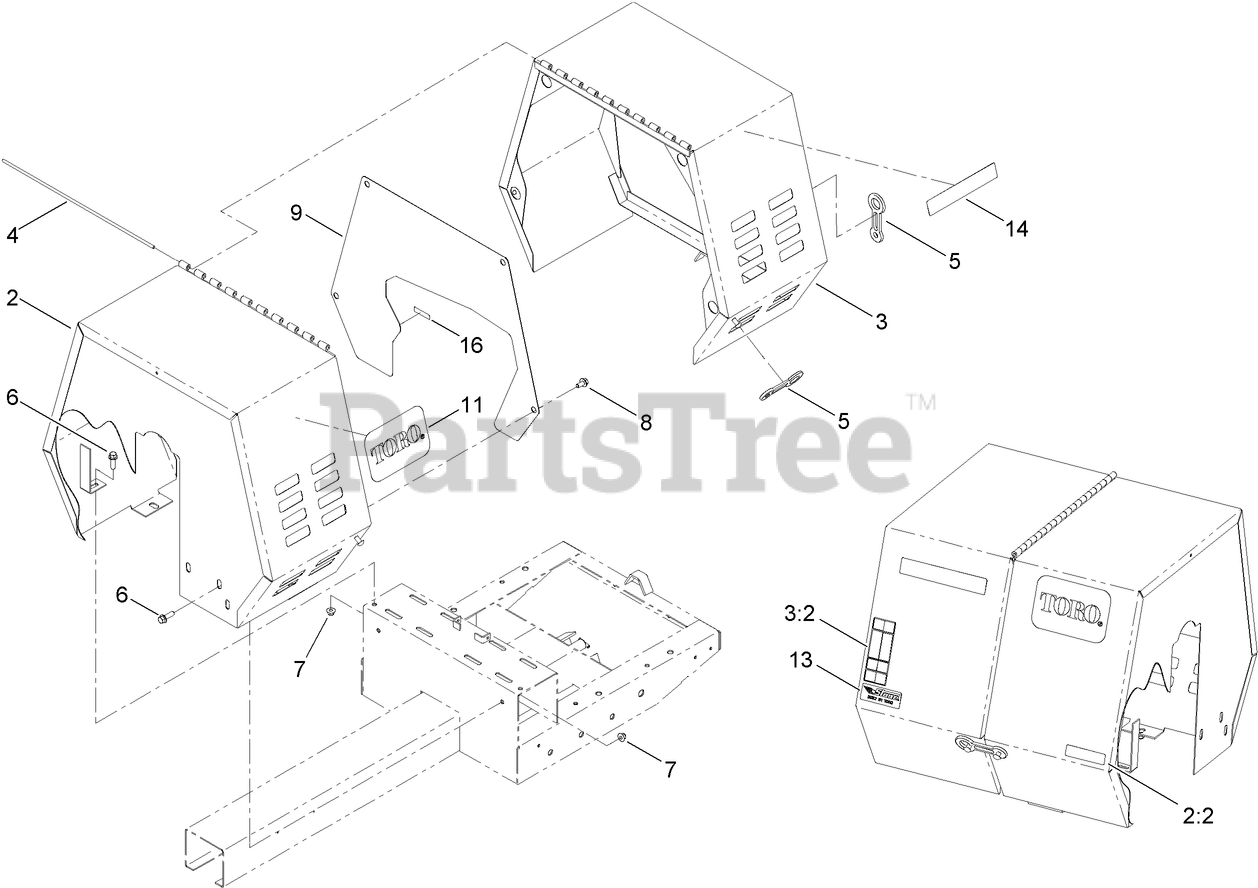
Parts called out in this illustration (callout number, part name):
2	STATIONARY COWL ASM
2:2	DECAL-ARRESTER, SPARK
3	MOVABLE COWL ASM
3:2	DECAL-WARNING
5	LATCH-RUBBER
6	SCREW-HHF
7	NUT-HF, NI
8	SCREW-HWH
9	PLATE-GUARD
11	DECAL
14	DECAL-MM-655H
16	DECAL-GREASE
